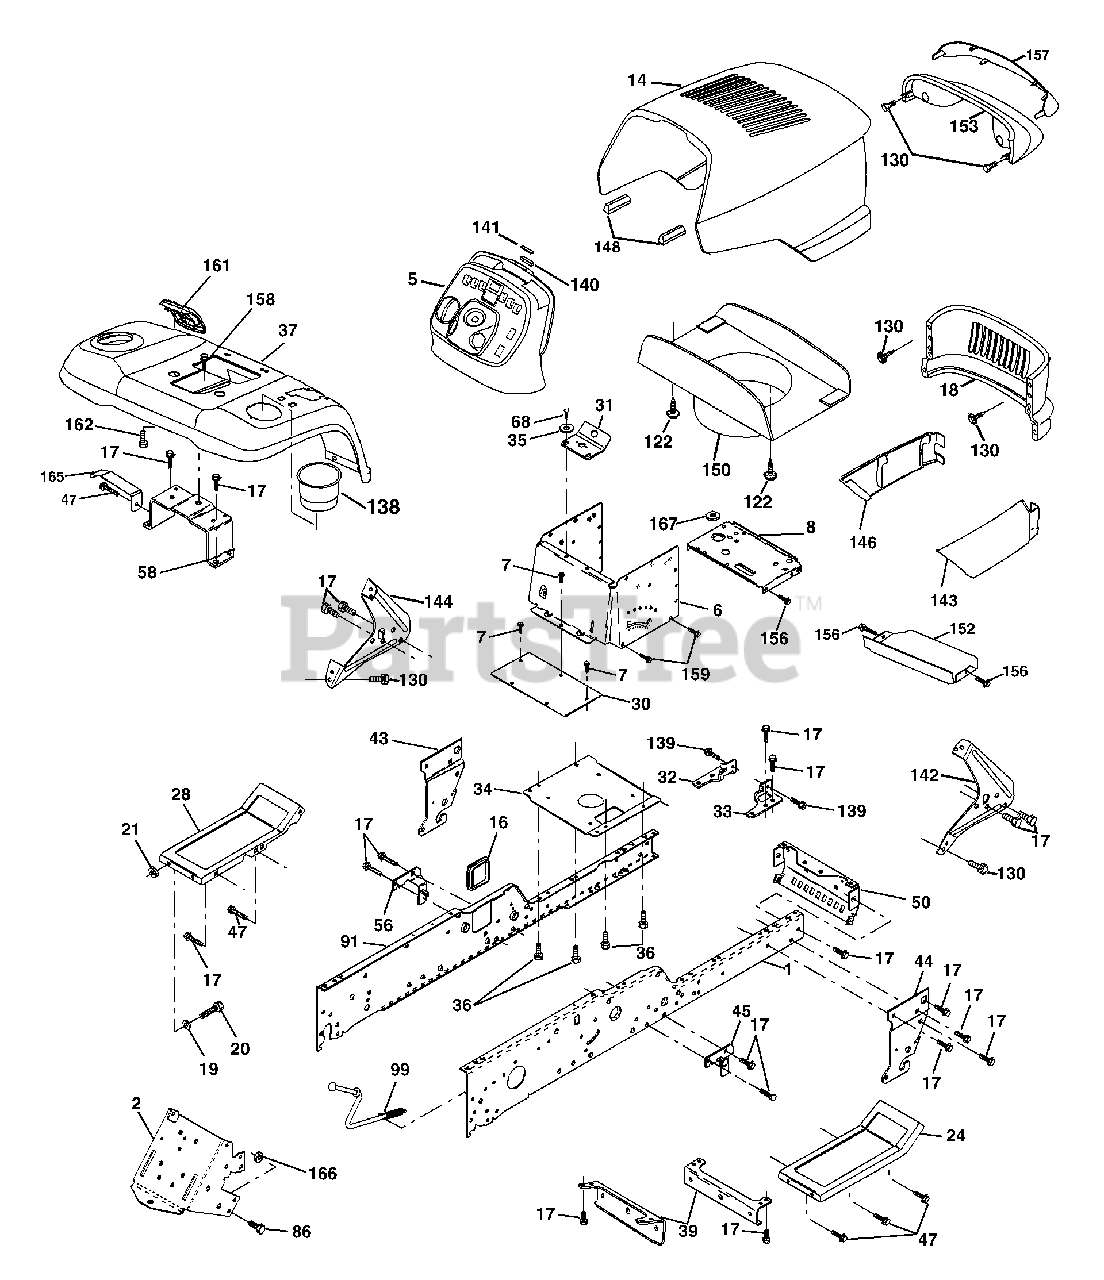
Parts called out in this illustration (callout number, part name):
1	Rail, Frame RH
2	Drawbar, Gt
5	Dash
6	Dash Asm., Lower
7	Screw, Thd Cut 1/4-20 x 1/2
8	Support, Battery
14	Hood Asm., Pnt
16	Cover, Access
17	Screw, 3/8-16 x 3/4
18	Grille
19	Washer 13/32 x 13/16 x 12 Ga.
20	Bolt, Fin Hex 3/8-16 x 1
21	Nut, Lock Hex w/Ins. 3/8-16 Unc
24	Footrest, RH
28	Footrest, LH
30	Saddle, Hydro 1995
31	Bracket, Supt 1-pc VGT Steering
32	Bracket, Pivot Chassis LH
33	Bracket, Pivot Chassis RH
34	Plate Asm. Engine Chassis
35	Washer 11/32 x 11/16 x 16 Ga.
36	Screw 5/16-18 x 3/4
37	Fender, Pnt.
39	Bracket, Axle Front
43	Bracket, Spnsn Front Lh
44	Bracket, Spnsn Front Rh
45	Bracket Asm., Susp Chassis Rh
47	Screw Thdrol 3/8-16 x 1/2 TYT
50	Bracket, Chassis Front
56	Bracket Asm., Susp Chassis Lh
58	Bracket Asm., Fender
68	Screw, Thd 5/16-18 x 1/2
86	Bolt, Fin Hex 7/16-14 Unc x 1
91	Rail, Frame Lh
99	Rod By Pass
122	Screw Hex Wshd 8-18 x 7/8
130	Screw HWHD Hi-Lo #13-16 x 3/4
138	Cupholder YTGT
139	Bolt Shoulder 5/16-18 TT
140	Magnet YTGT
141	Stricker Plate YTGT
142	Bracket Dash RH
143	Skirt Grill RH
144	Bracket Dash LH
146	Skirt Grill LH
148	Extrusion Bumper
150	Duct Heat Hood
152	Shield Browning
153	Light Box Asm. w/Lens
156	Screw 5/16-18 x 3/4
157	Lens, Bar
158	Screw Thdrol 3/8-16 x 1/2
159	Screw 3/8-16 x 3/4
161	Console Fuel Window
162	Screw 1/4-1/2
165	Bracket Support Tank
166	Nut, Crownlock 7/16-14Unc
167	Bushing Snap
